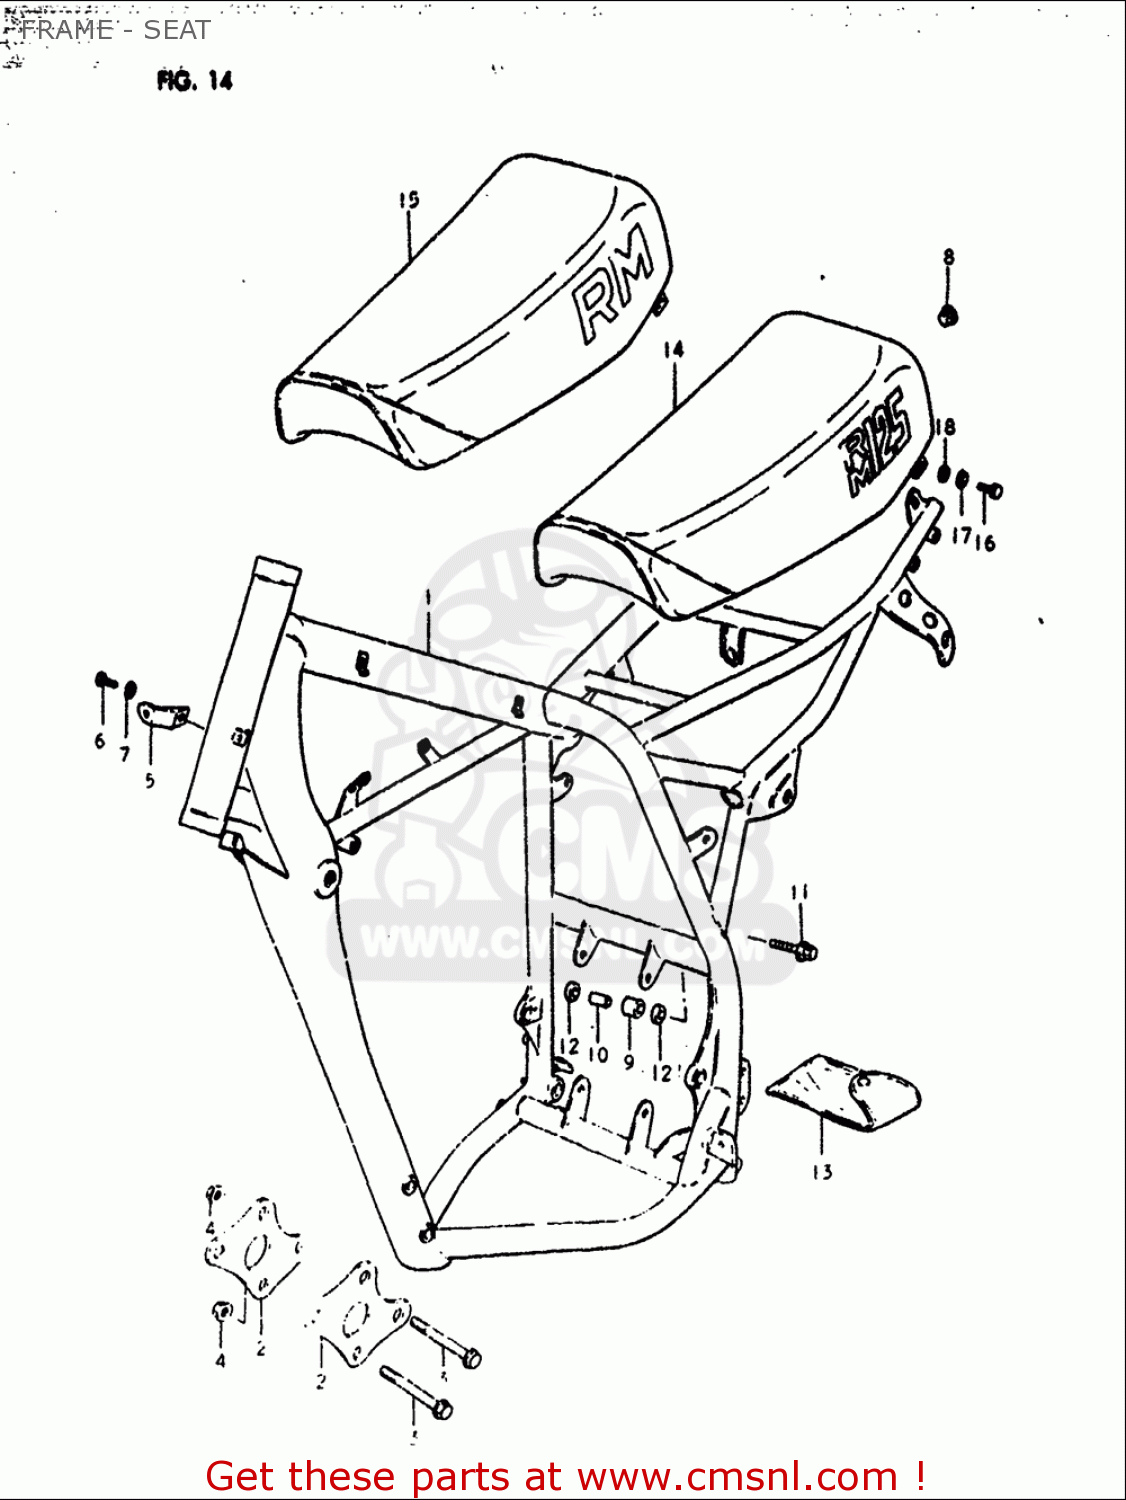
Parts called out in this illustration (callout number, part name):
3	BOLT(8X67)
4	NUT
6	BOLT
7	WASHER,LOCK
8	PLUG(OD:19)
9	ROLLER,CHAIN LENGTH CONTROL
10	SPACER,CHAIN LENGTH ROLLER
11	BOLT(8X45)
12	WASHER(8.5X24X1.6)
16	BOLT
17	WASHER,LOCK
18	WASHER(6.5X18X1)
